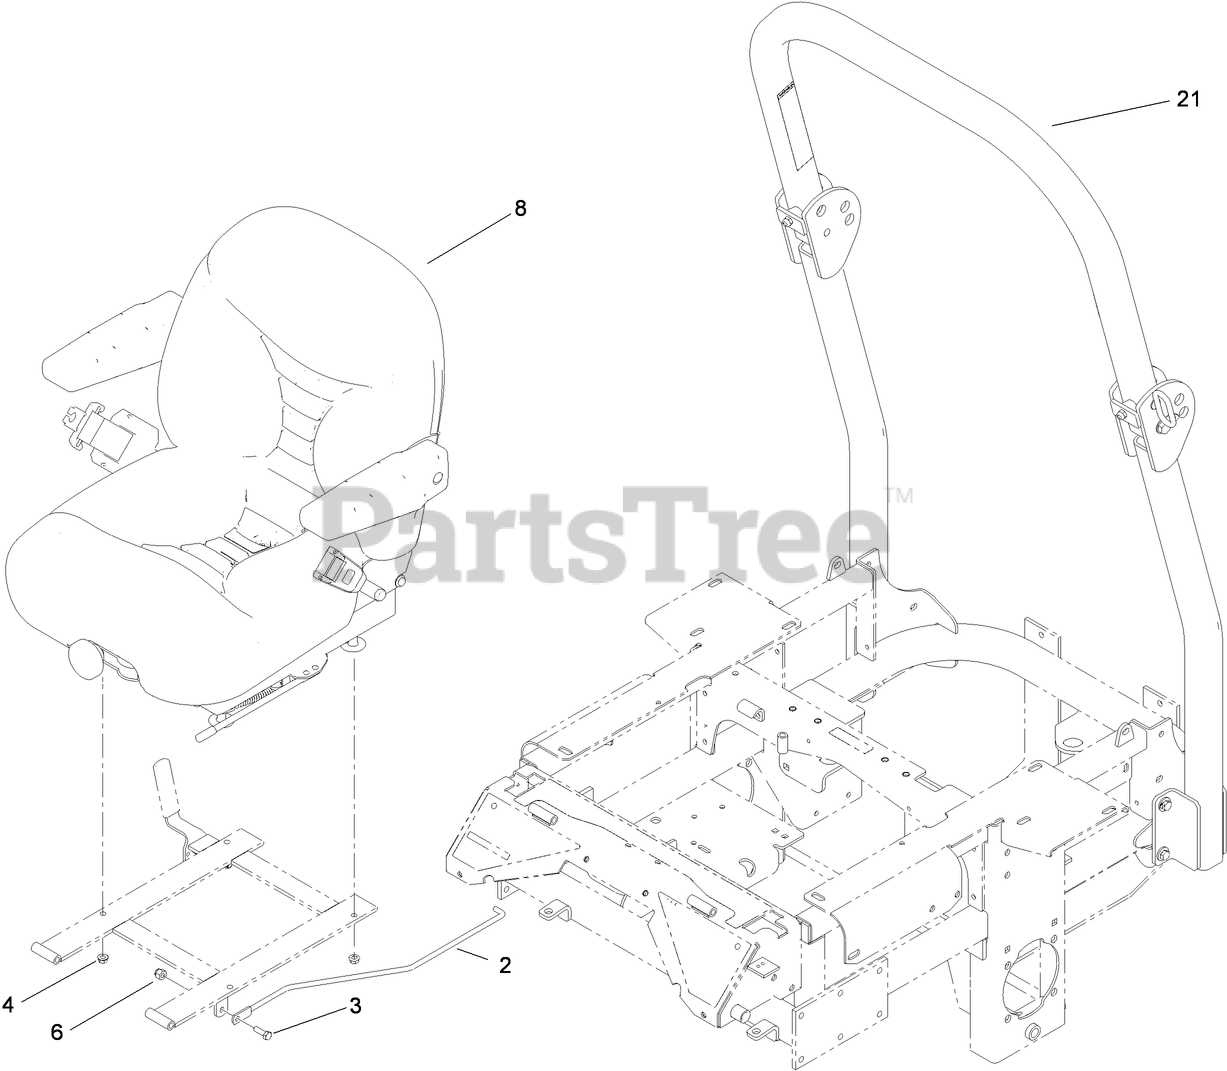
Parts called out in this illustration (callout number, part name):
2	ROD-PROP, SEAT
3	SCREW-HH
4	NUT-HF
6	NUT-LOCK, NI
8	DELUXE SEAT ASM
21	ROPS KIT
